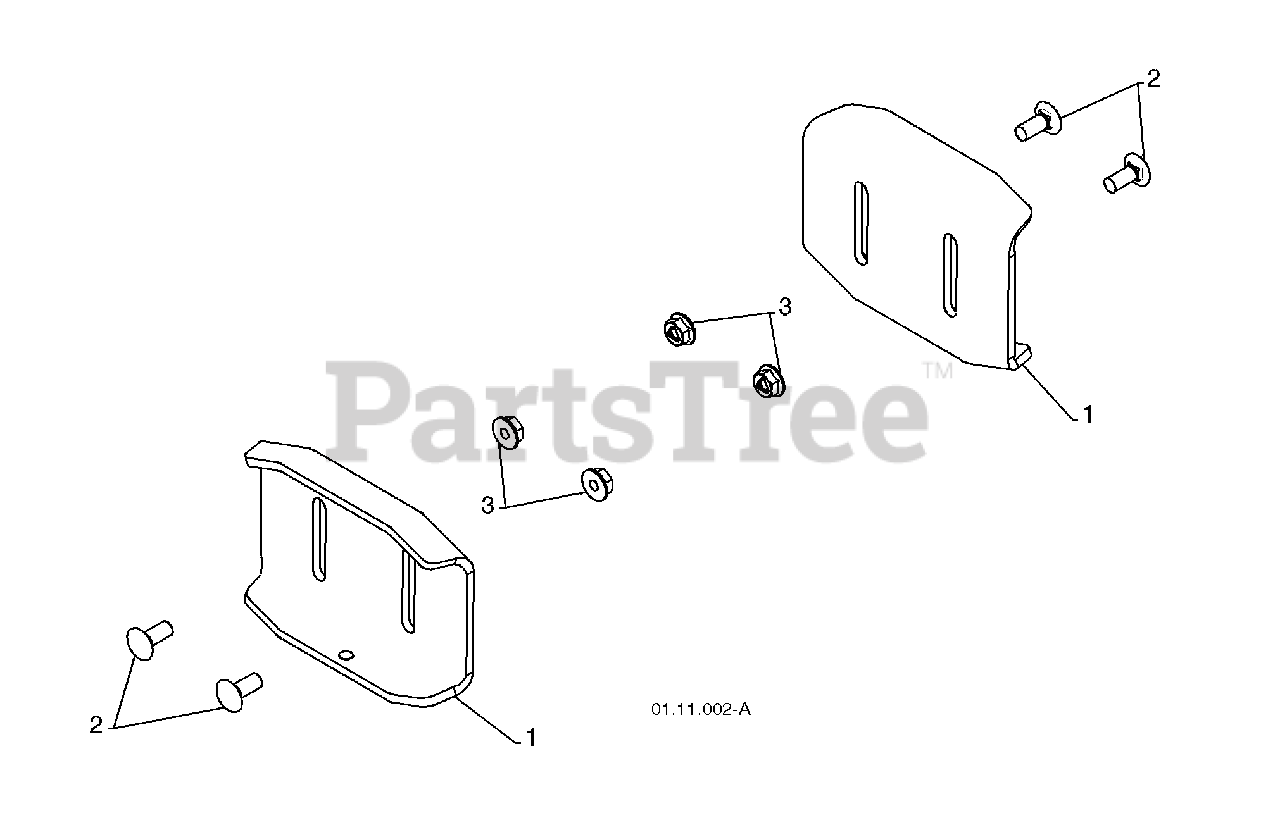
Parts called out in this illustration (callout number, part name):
1	SKID PLATE
2	CARRIAGE BOLT 5/16-18 X .750
3	NUT 5/16-18
